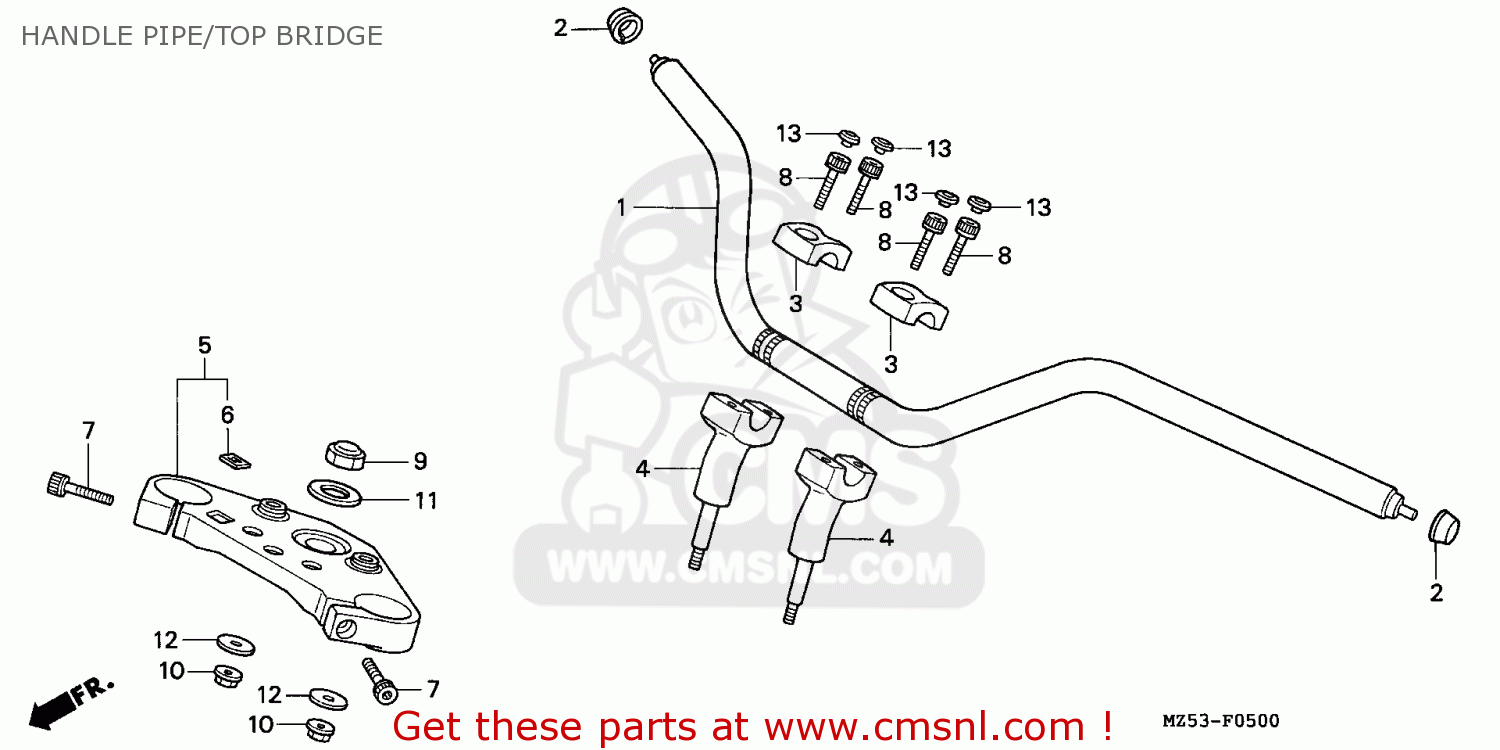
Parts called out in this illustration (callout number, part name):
1	PIPE,STRG.HANDLE
3	HOLDER,HNDL.UPP
4	HOLDER,HANDLE LOW
5	BRIDGE COMP,FORK
6	EMBLEM,WING MARK
7	BOLT,SOCKET 8X30
8	BOLT,SOC,8X32
9	NUT,STEERING STEM
10	NUT,FLANGE,8MM
11	WASHER, STEM
12	WASH.HNDL.HOLDER
13	CAP,SOC.BOLT 8MM
